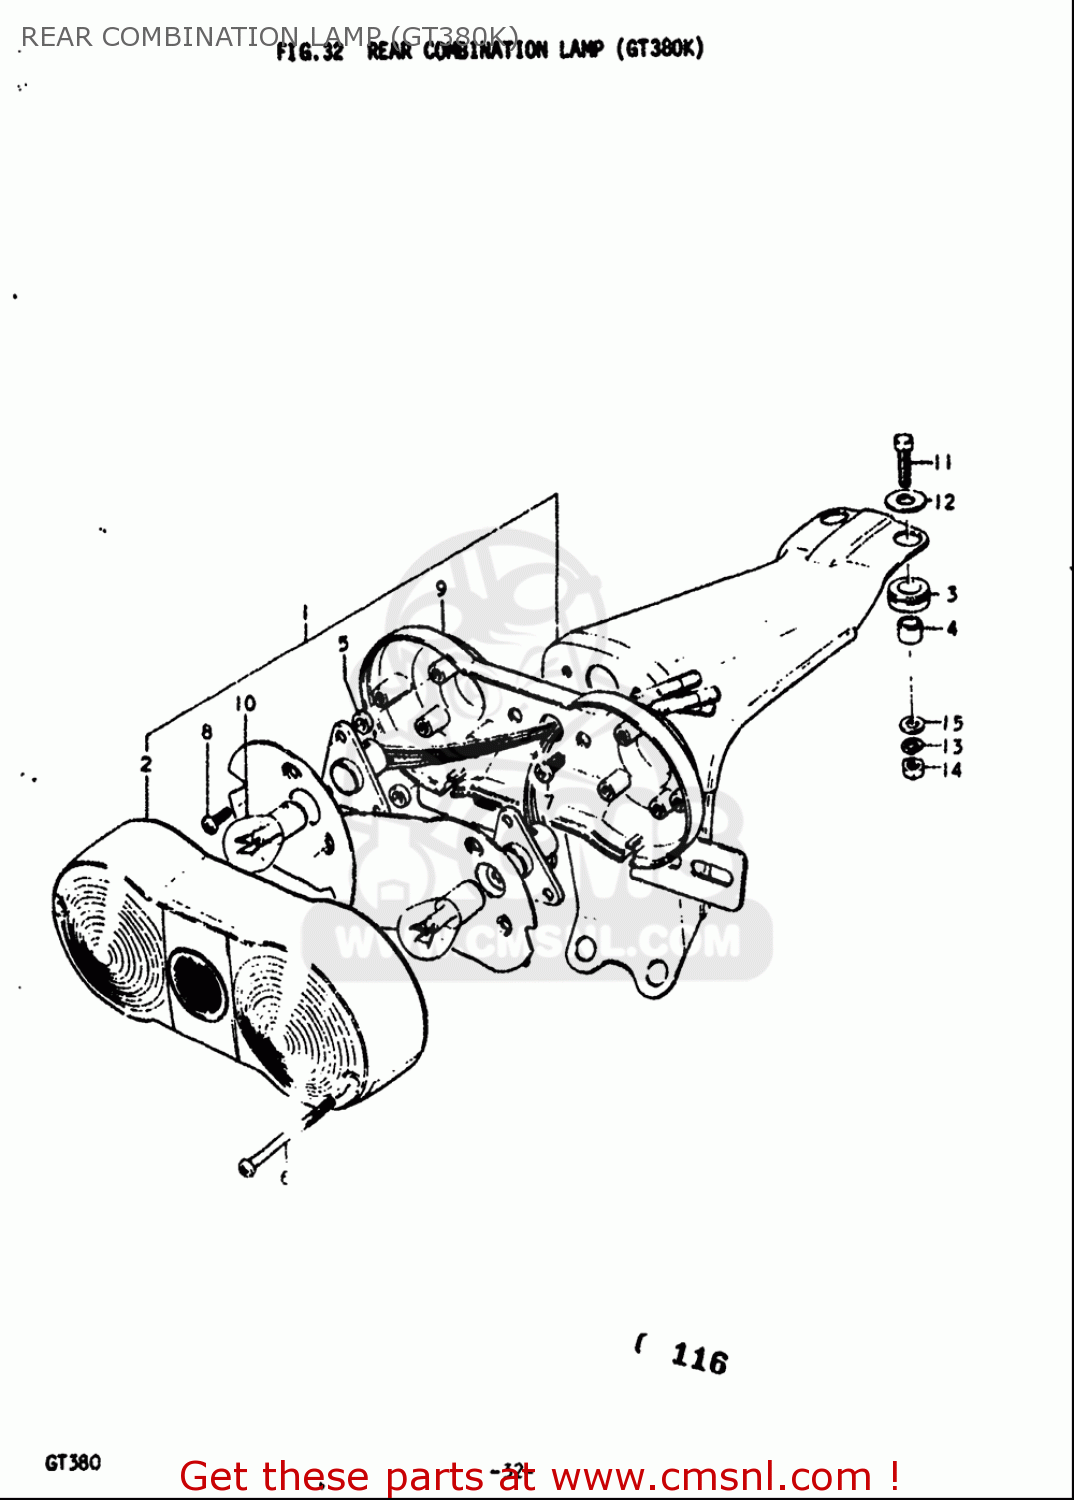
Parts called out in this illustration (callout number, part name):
2	LENS,REAR COMBINATION LAMP
3	CUSHION
4	SPACER
6	SCREW
7	SCREW
8	SCREW
10	BULB(12V23W)
11	BOLT 6X23
12	WASHER(6.5X20X1.6)
13	WASHER,LOCK
14	NUT
15	WASHER
